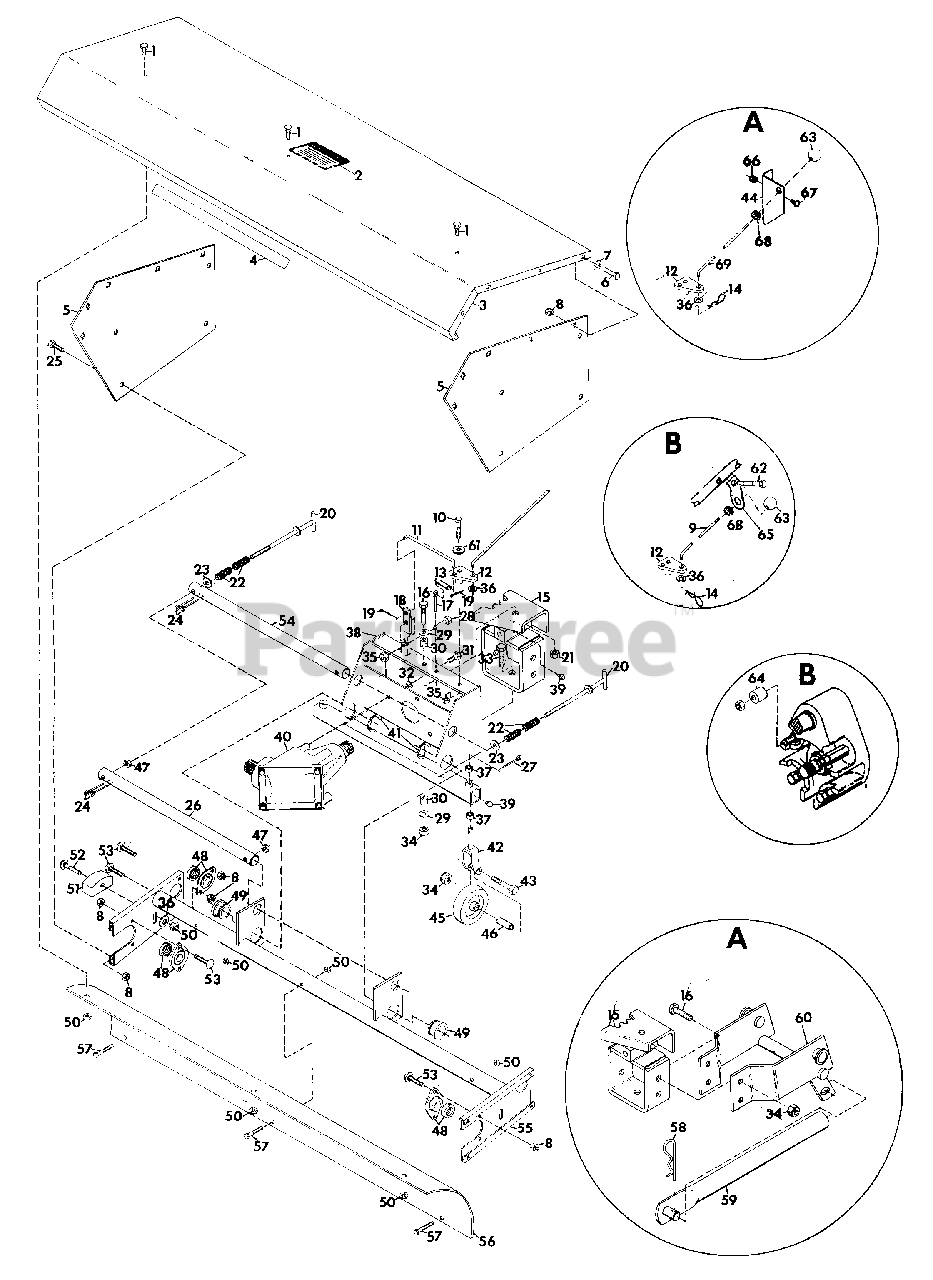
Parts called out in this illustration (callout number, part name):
1	BOLT, HEX 1/4-20X.50
2	DECAL, CAUTION
3	HOOD
4	DECAL, GRAVELY LOGO
5	PLATE, SIDE
6	BOLT, HEX 5/16-18X.625
7	WASHER, FLAT .344X.688X.065
8	NUT, LOCK 5/16-18
9	ARM, CONTROL WALKING TRACTORS
10	BOLT, HEX 3/8-16X2.25
11	ROD, LINKAGE
12	WELDMENT, BRACKET
13	SPRING, EXTENSION .62X.75X11.8 RATE
14	PIN, COTTER HAIR
15	WELDMENT, PIVOT POWER BRUSH
16	BOLT, HEX 1/2-13X1.50
17	PIN, COTTER .375X1.375
18	PLATE, LOCKING
19	PIN, COTTER .125X.750
20	WELDMENT, ROD
21	NUT, LOCK 1/2-13
22	SPRING, COMP. 1X.78X338 RATE
23	WASHER, FLAT .531X1.250X.100
24	PIN, COTTER .125X1.500
25	BOLT, HEX 5/16-18X.75
26	ANCHOR, THREADED ADJUSTMENT
27	PIN, COTTER .125X1.250
28	BOLT, HEX 3/8-16X1.50
29	WASHER, FLAT .531X1.062X.095
30	BUSHING, PIVOT CASTING
31	BOLT, HEX 1/2-13X1.00
32	WASHER, LOCK 1/2 REG.
33	BOLT, HEX 1/2-13X1.75
34	NUT, LOCK 1/2-13
35	NUT, LOCK 3/8-16
36	WASHER, FLAT .281X.625X.065
37	BEARING, BRONZE .751X.877X.750
38	WELDMENT, PIVOT FRAME
39	FITTING, LUBE 1/4-28
40	ASSEMBLY, GEAR BOX
41	E-RING 1.375 SHAFT
42	WELDMENT, CASTER FORK
43	BOLT, HEX 1/2-13X3.75
44	BRACKET
45	WHEEL, CASTER
46	BUSHING, .515X.750X2.594
47	NUT, HEX 1/2-13
48	BEARING, FLANGETTE
49	BUSHING
50	NUT, LOCK 1/4-20
51	BLOCK, TENSION
52	BOLT 1/4-20X2.00 RD HD SQ NK
53	BOLT, CARRIAGE 5/16-18X.75
54	ANCHOR, ADJUSTMENT
55	FRAME, BRUSH SUPPORT
56	SHIELD
57	BOLT, HEX 1/4-20X2.25
58	PIN, HAIR
59	ROD, PUSH WELDMENT
60	WELDMENT, ADAPTER
61	WASHER, FLAT .406X.812X.065
62	BOLT, HEX 1/2-13X2.75
63	KNOB
64	BUSHING .531X1.000X.600
65	GUIDE, CONTROL ROD
66	GROMMET, PLASTIC
67	SCREW, TAPPING 1/4-20X.625 PHD
68	GROMMET, SHIFTER
69	ROD, CONTROL
